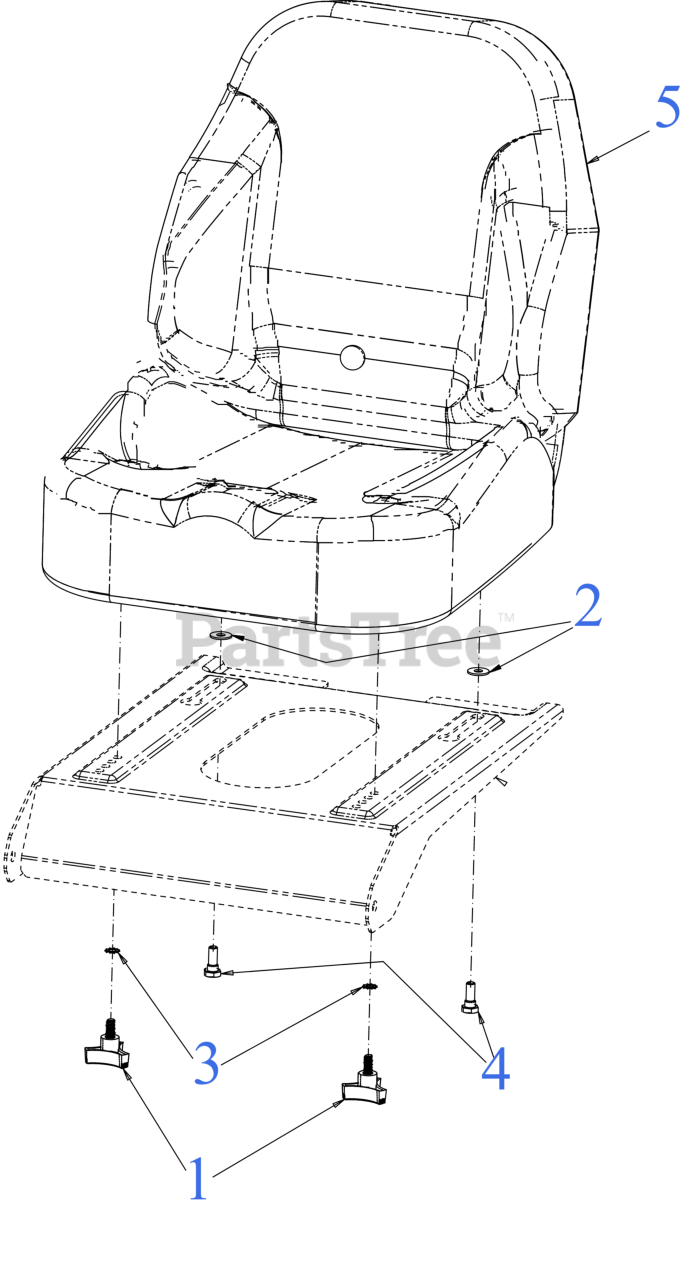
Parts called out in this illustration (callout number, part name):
1	3 PRONG KNOB 5/16-18
2	FLAT WASHER
4	SHOULDER SCREW .437
5	SEAT (CUB)
